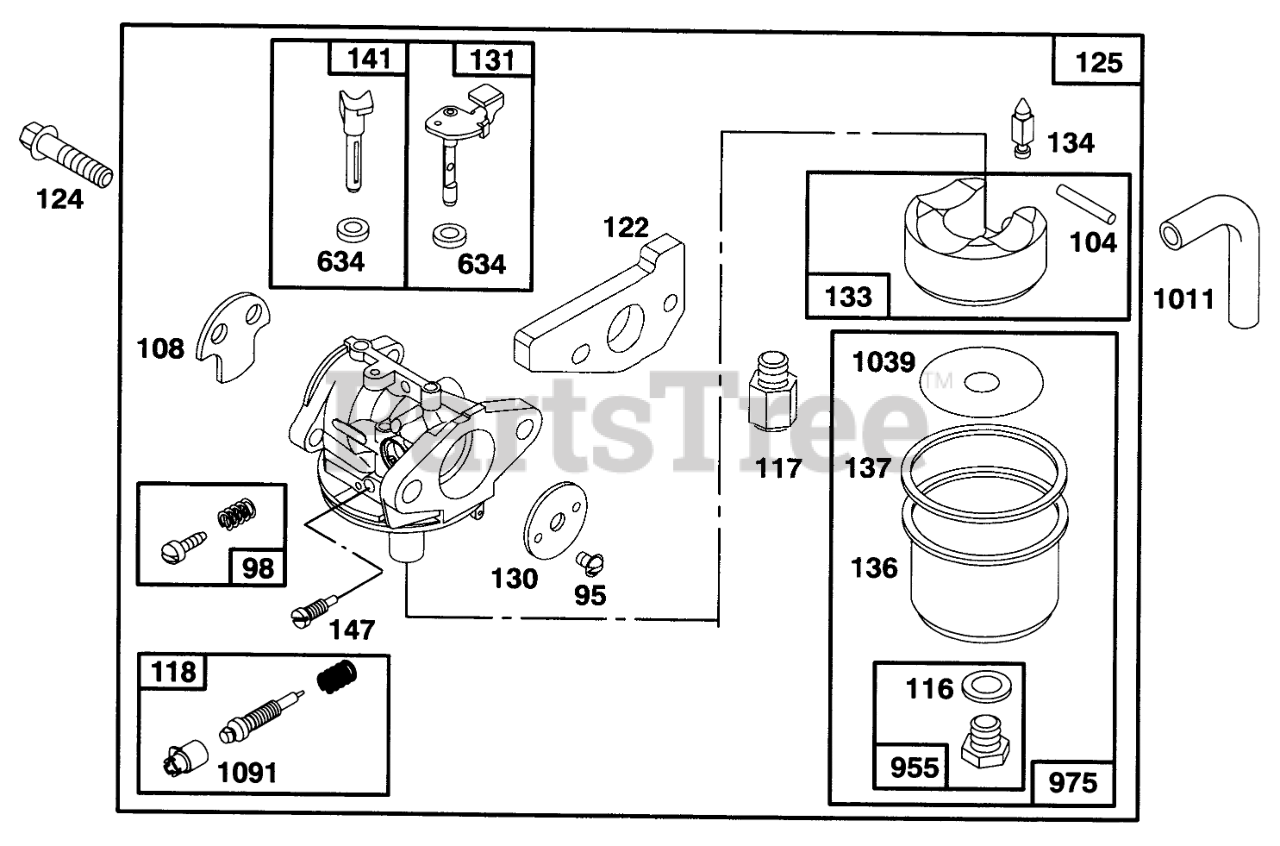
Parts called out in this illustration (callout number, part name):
95	SCREW - ROUND HEAD
98	IDLE ADJUSTING SCREW
104	FLOAT HINGE PIN
108	VALVE - CHOKE
116	SEALING GASKET
117	Jet-Main
118	VALVE/SPRING - NEEDLE
122	ADAPTER ASSEMBLY
124	HEX HEAD SCREW
125	ASSEMBLY - CARBURETOR
130	THROTTLE VALVE
131	THROTTLE SHAFT
133	FLOAT-CARBURETOR
134	Valve-Inlet (Includes Seat)
136	FLOAT BOWL
137	FLOAT BOWL GASKET
141	CHOKE SHAFT
147	JET - PILOT
634	SEAL WASHER
955	HEX HEAD SCREW
975	CARBURETOR BOWL ASM
1011	VENT TUBE
1039	FLOAT LIMITER
1091	CAP - LIMITER
